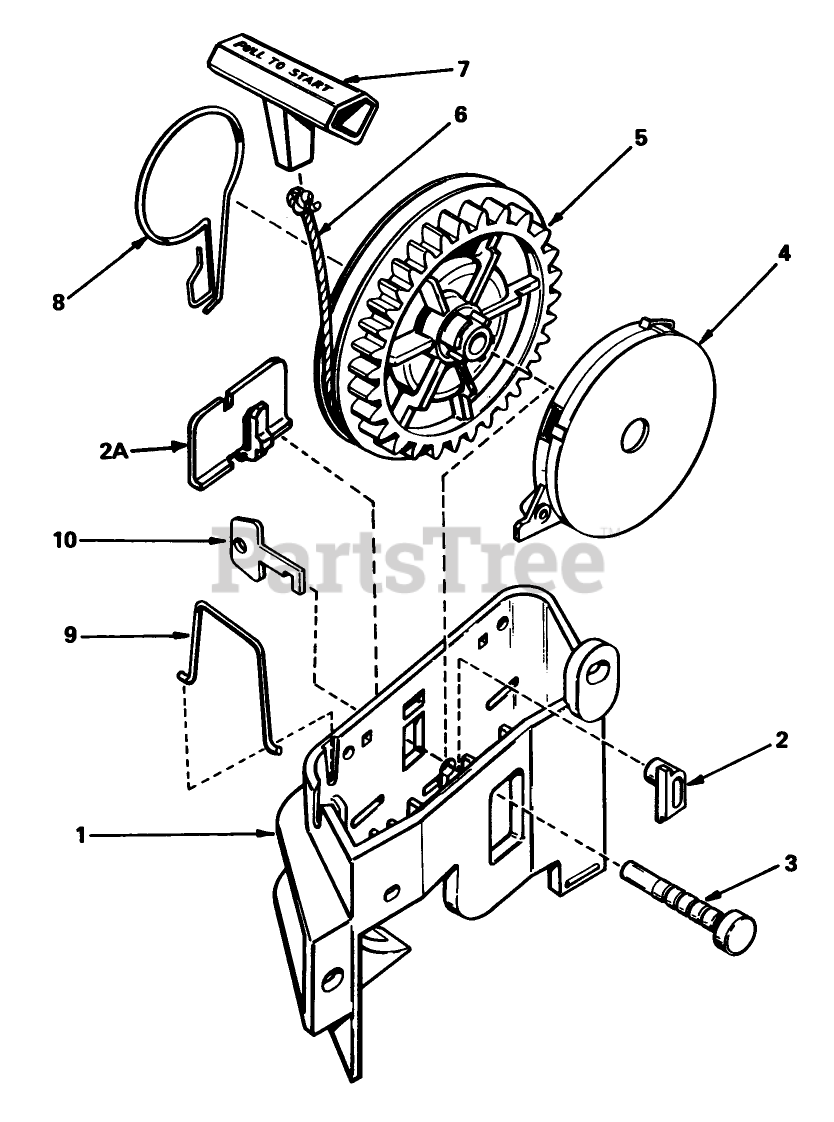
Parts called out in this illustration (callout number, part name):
1	Bracket Starter
2	Pawl, Locking Not used on all engine models)
2A	Clip, Starter Bracket (Used On Starters Not Equipped With Pawl, Ref. No. 2)
3	Pin-Pulley
4	Spring Assy., Rewind (Incl. Ref. #3)
5	Pulley
6	Rope Starter (Length 65" 9/64" Dia.)
7	Handle-Starter
8	Brake
9	Clip-Rope
10	Key (Not Used On All Engine Models
